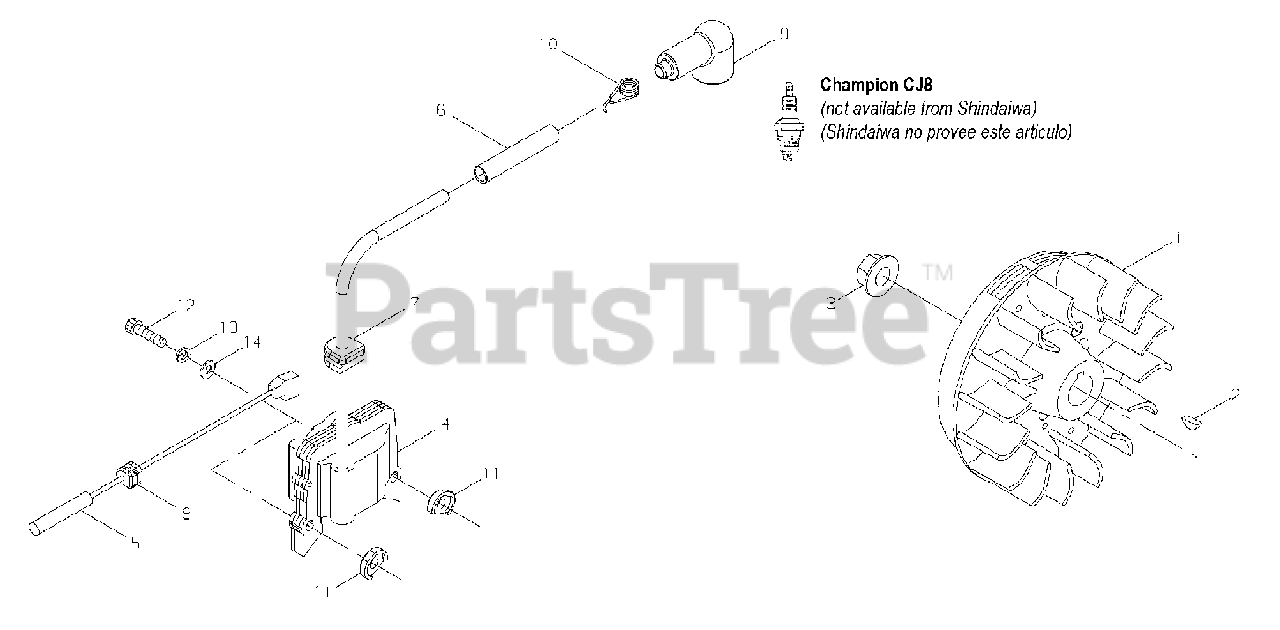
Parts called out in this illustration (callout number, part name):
1	FLYWHEEL
2	KEY, WOODRUFF 3×10
3	NUT, FLANGE M10
4	COIL, IGNITION
5	LEAD - IGNITION
6	TUBE, INSULATOR
7	GROMMET
8	GROMMET, LEAD
9	CAP, SPARK PLUG
10	TERMINAL, SPARK PLUG
11	COLLAR 4
12	BOLT M4×24
13	WASHER, SPRING 4 MM
14	WASHER 4.3×9.6×0.8
